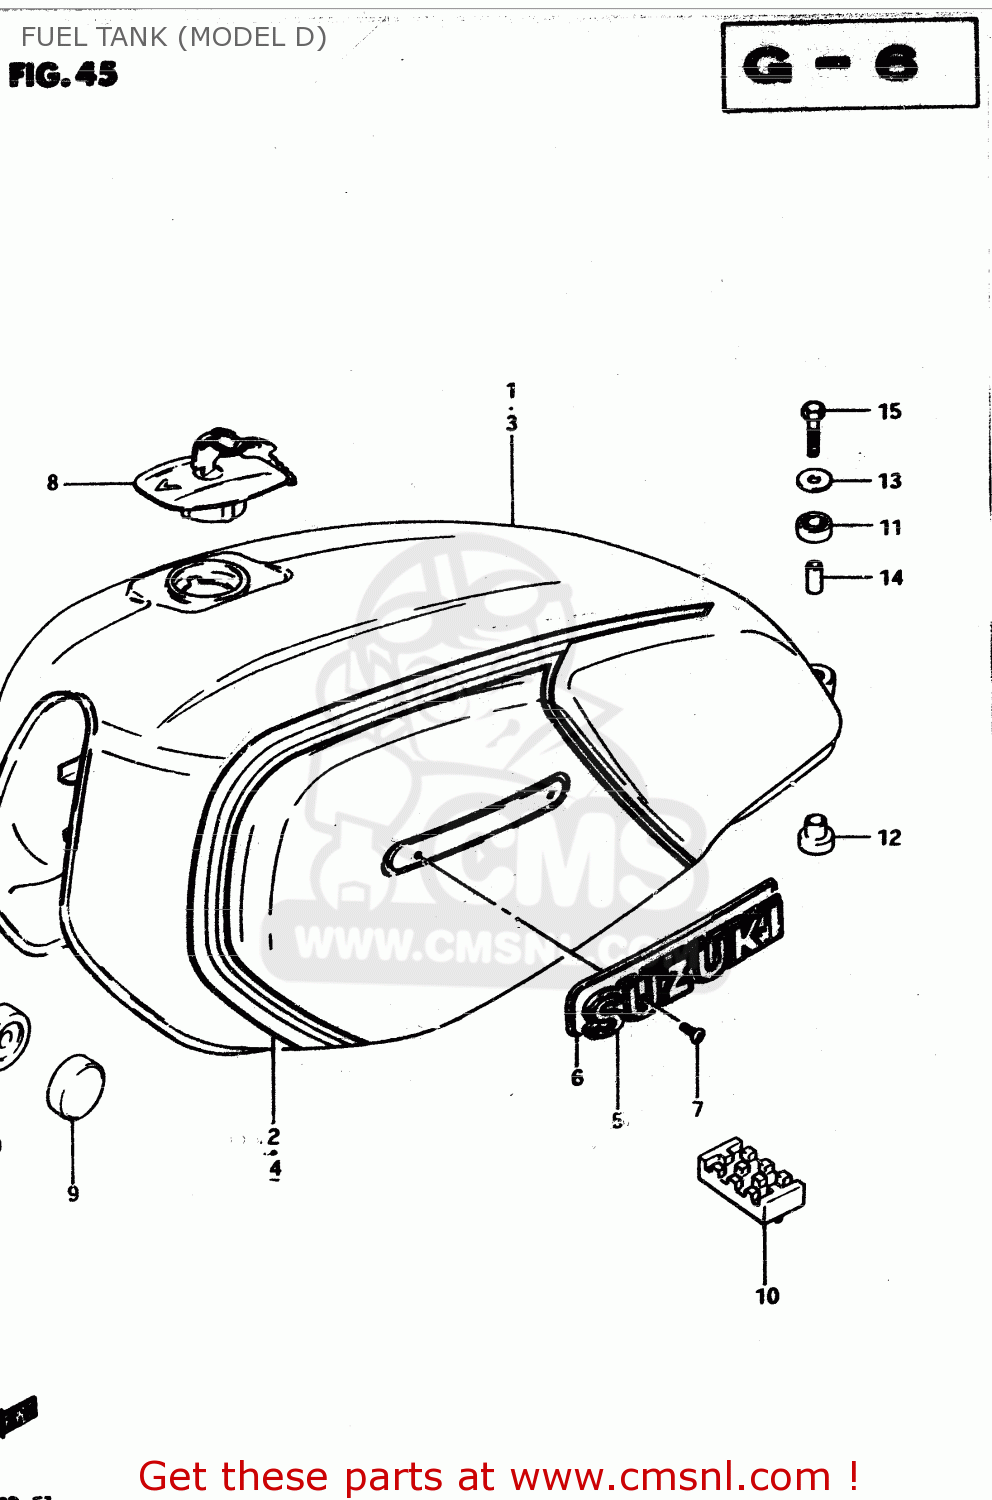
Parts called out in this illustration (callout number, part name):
1	TANK, FUEL
2	TAPE SET
3	TANK, FUEL
4	TAPE SET
5	EMBLEM,FUEL TANK
6	CUSHION, EMBLEM
7	SCREW 3X6
8	CAP SET,FUEL TANK
9	CUSHION
10	CUSHION,FUEL TANK
11	CUSHION
12	CUSHION
13	WASHER (6.5X24X1.6)
14	SPACER (6.4X9X21.5)
15	BOLT
